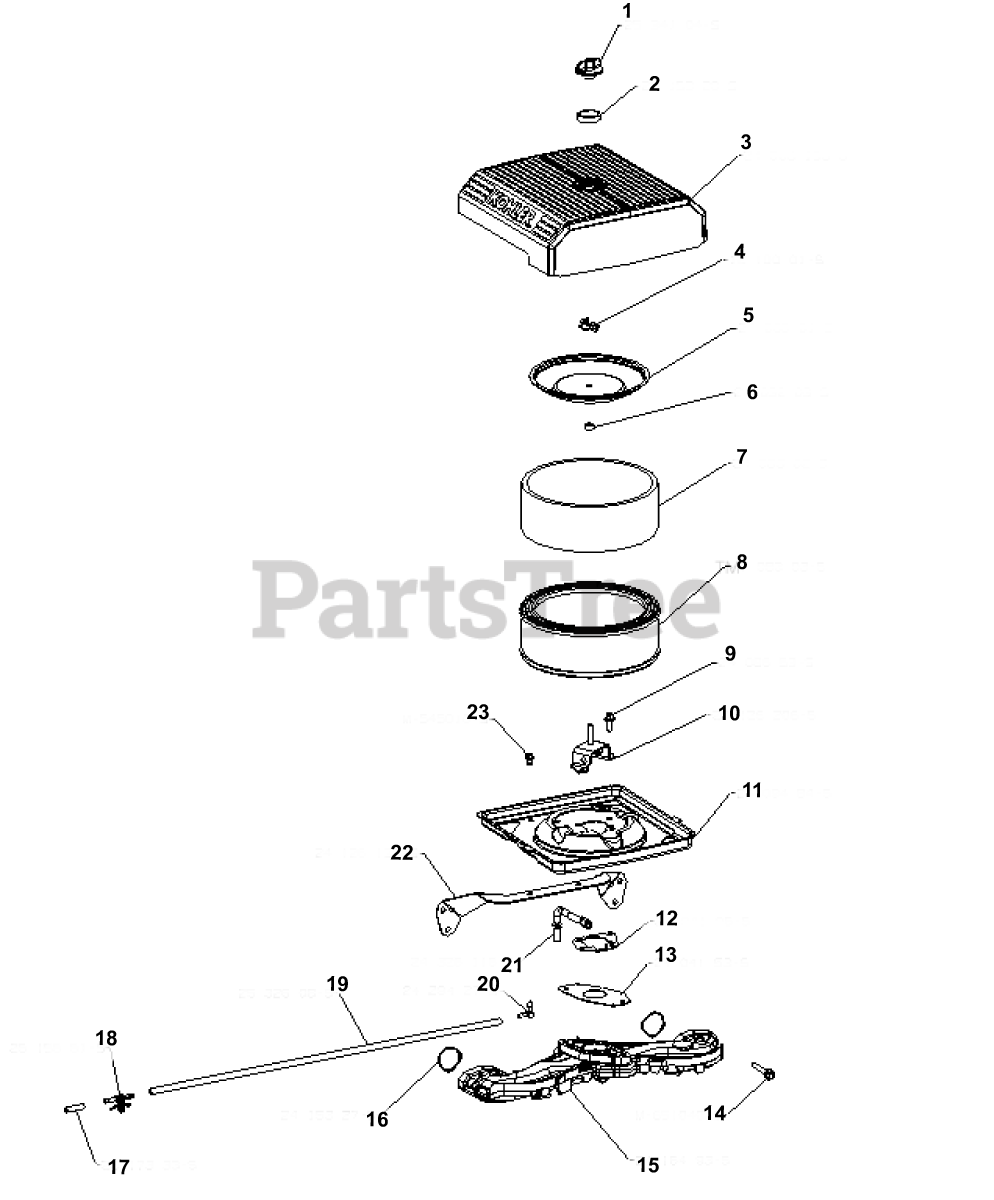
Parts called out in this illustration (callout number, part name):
1	KNOB, COVER
3	COVER, AIR CLEANER
4	NUT, WING
5	COVER, INNER AIR CLEANER
6	SEAL, INNER AIR CLEANER
7	ELEMENT, PRECLEANER (LOW)
8	ELEMENT, AIR CLEANER - Also available Retail Packaged 47 883 03-S1 Air Filter Kit
9	SCREW, FLG THD FRM M6X1.0X16
10	BRACKET, AIR CLEANER
11	KIT, AIR CLEANER BASE
12	GASKET, AIR CLEANER BASE
13	GASKET, CARBURETOR
14	SCREW, FLG M6X1.0X40
15	KIT, INTAKE MANIFOLD
16	O-RING, INTAKE PORT
17	CAP, MASKING
18	CONNECTOR, EVAPORATIVE
19	HOSE, EVAPORATIVE 20"
20	CONNECTOR, EVAPORATIVE HOSE
21	HOSE, EVAPORATIVE-USE 24 326 131-S
22	BRACKET, AIR CLEANER BASE
23	SCREW, FLG THD FRM M5X.8X10
5475501-S	KIT, KNOB W/SEAL
